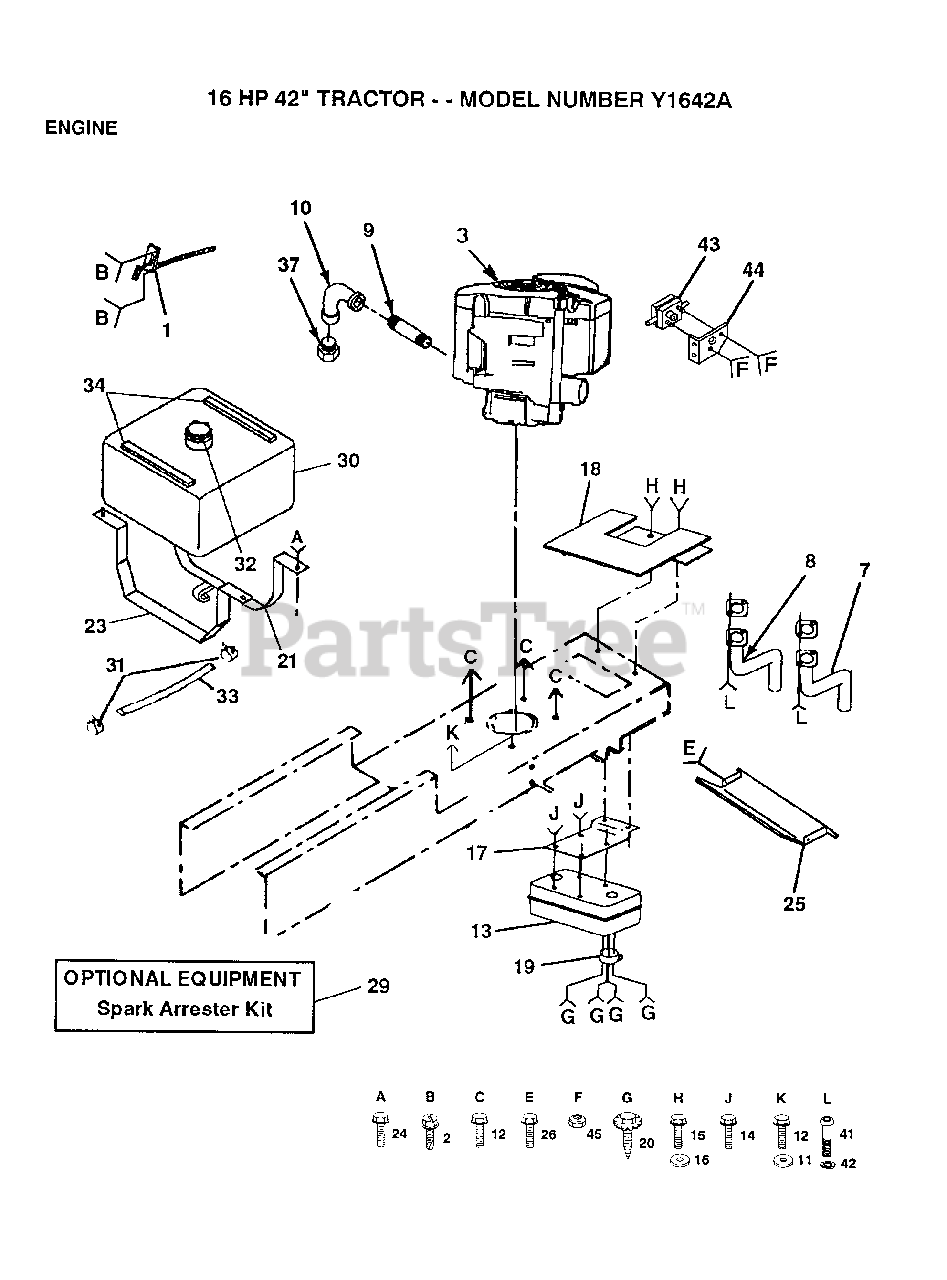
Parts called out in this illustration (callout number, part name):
1	THROTTLE CONTROL
2	SCREW LT
7	"TUBE,MANIFOLD RH"
8	"TUBE,MANIFOLD LH"
9	PIPE NIPPLE LT
10	ELBOW
11	LOCKWASHER
12	SCREW LT
14	SCREW ST
15	SCREW
16	WASHER
17	BRACKET MUFFLER
19	DEFLECTOR.222573
21	STRAP ASM. F.TANK
23	"STRAP,TANK"
24	SCREW LT
25	HEAT SHIELD
26	SCREW
31	HOSE CLAMP
33	FUEL LINE T
34	"STRIP,FORM"
41	SCREW
42	LOCKWASHER
44	"BRKT, FUEL PUMP"
